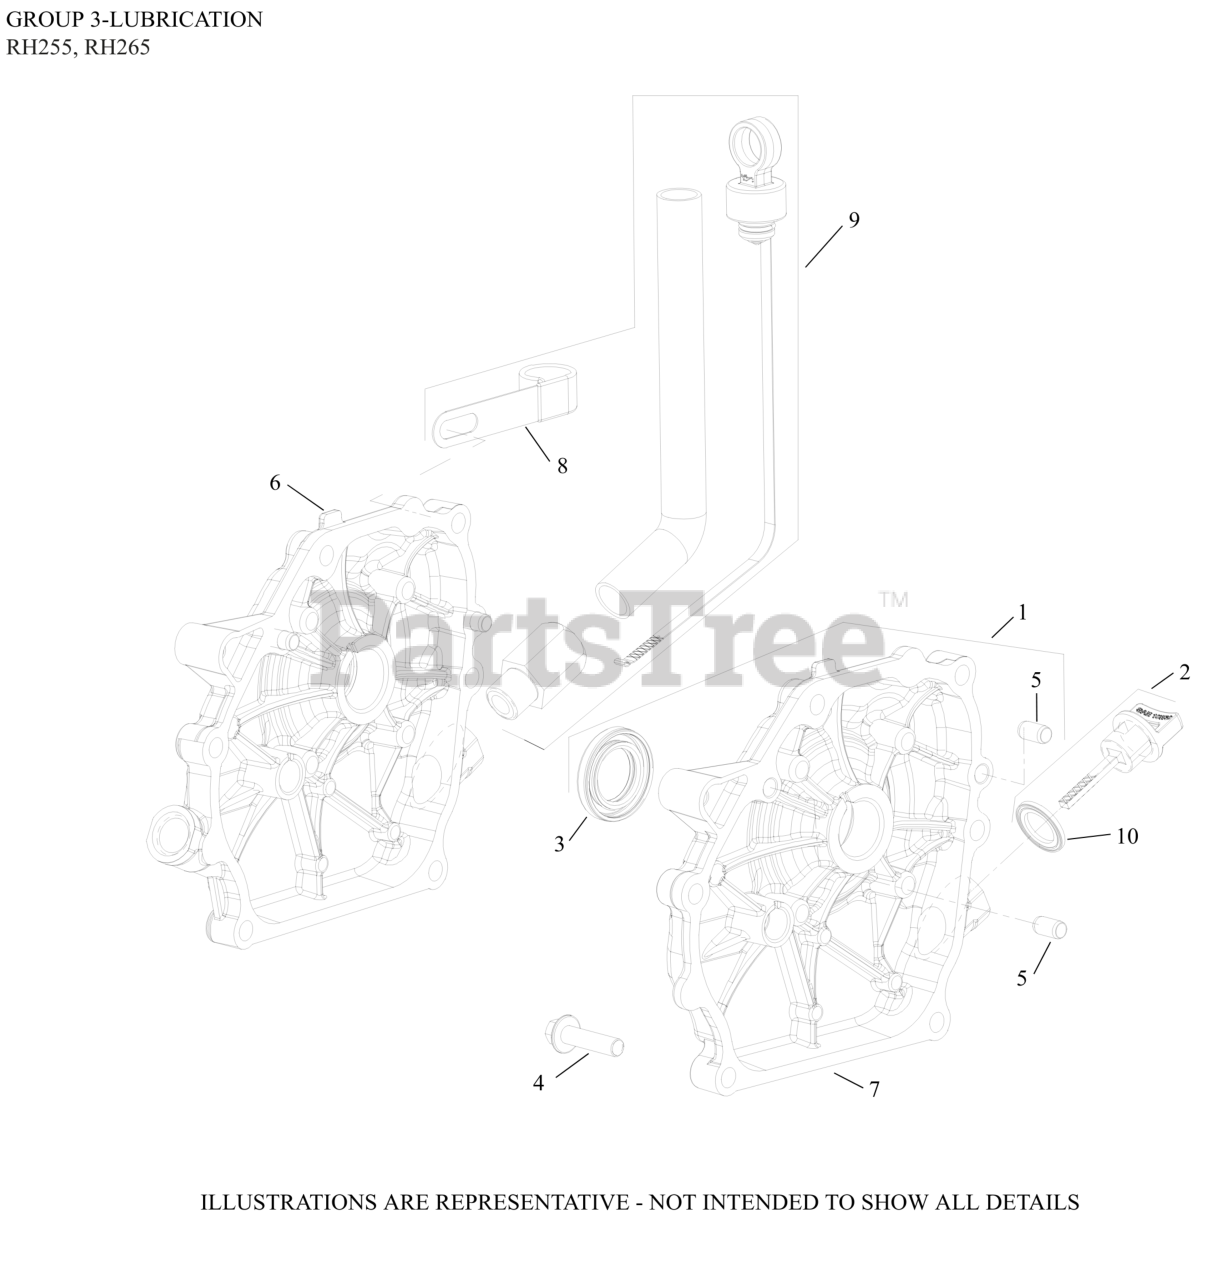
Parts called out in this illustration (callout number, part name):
1	PLATE, CLOSURE ASSEMBLY
2	DIPSTICK ASSEMBLY
3	SEAL - USE 17 032 29-S
4	SCREW, CLOSURE PLATE
10	GASKET, DIPSTICK
